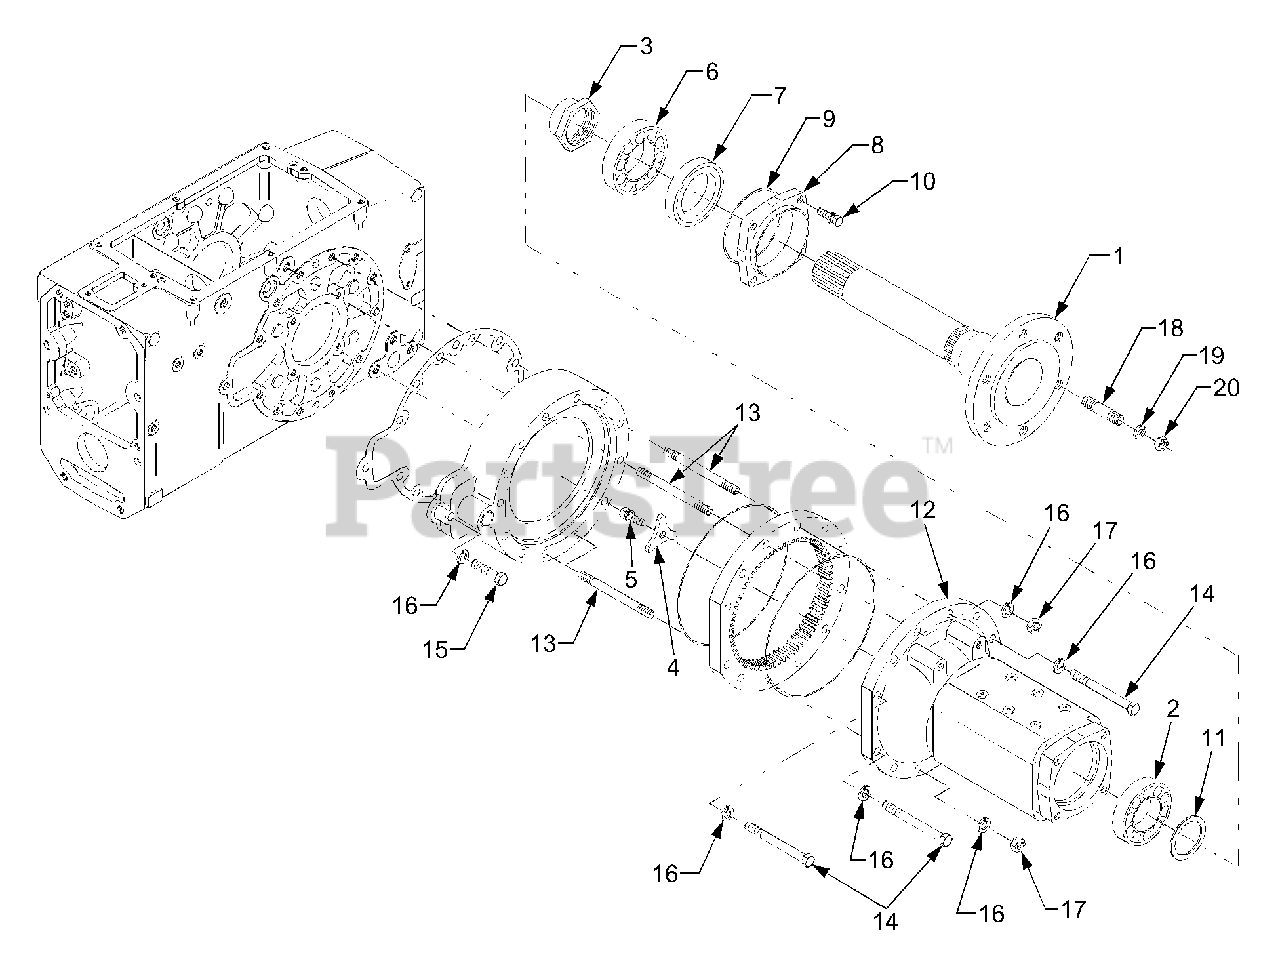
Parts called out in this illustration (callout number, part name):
2	Bearing, Ball
6	Bearing, Ball
8	Cover,rear Axle Bearing
12	Case, Rear Axle
16	Washer, Spring
19	Washer, Spring
